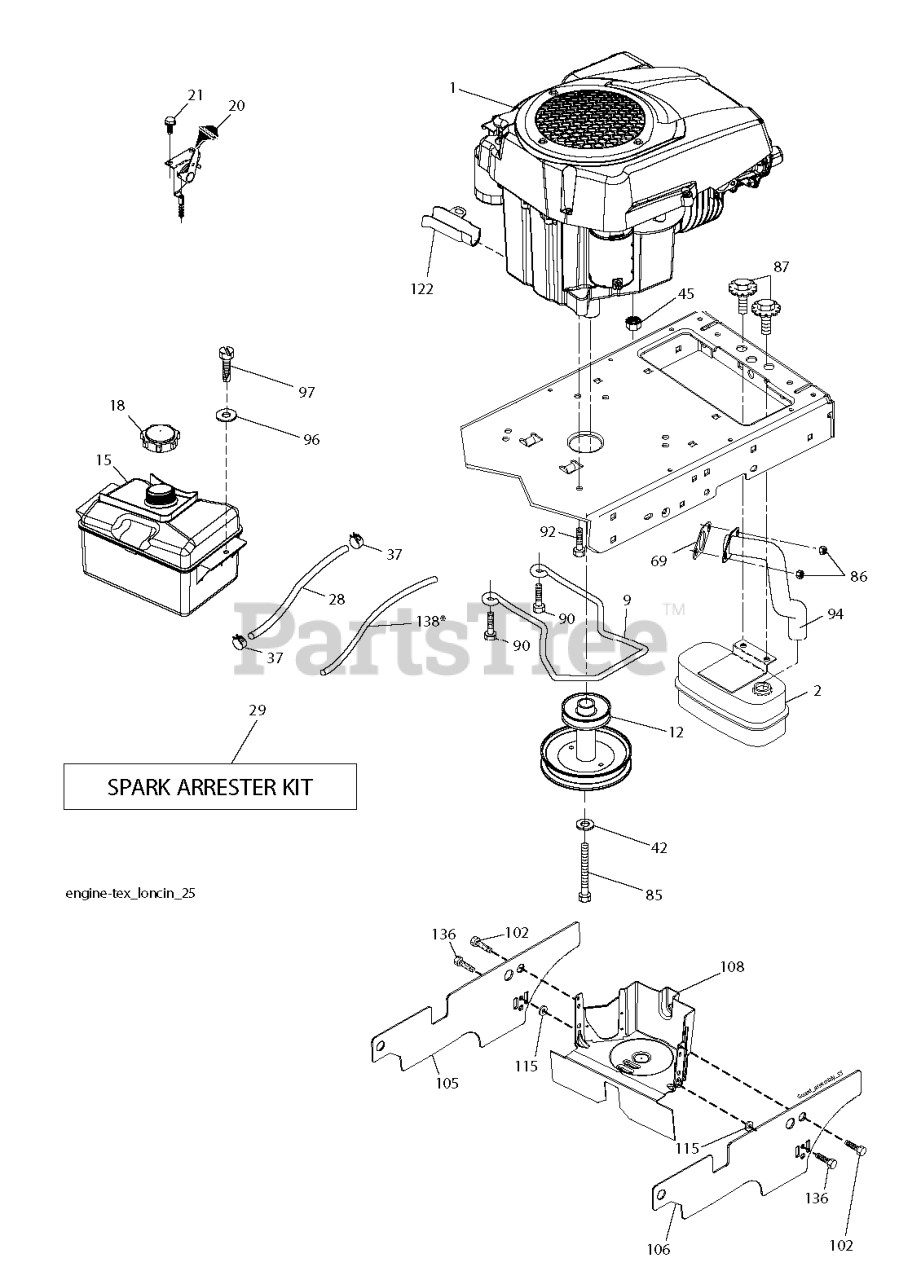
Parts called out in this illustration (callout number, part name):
1	ENGINE.LONCIN.SPARE/452
2	MUFFLER.ASM.SINGLE
12	ENGINE.PULLEY
15	FUEL TANK
15	FUEL.TANK.ASM.NON-EPA
18	CAP.2.25'.VENTED.RATCHET.EPA
20	CONTROL.TH/CK.C.BLACK
28	HOSE 1/4" LOW PERMEATION FUEL
29	KIT.SPARK ARRESTOR 794945 B&S
37	HOSE CLAMP
45	NUT HEXAGON WITH FLANGE, SERRA
69	GASKET GASKET.EXHAUST.LONCIN 3
79	Screws
85	BOLT.HEX.7/16-20X4.GR5.1.5BLUE
86	NUT.HEX.FLANGE.TOPLOCK
87	BOLT.5/16-18UNCX3/4 W/SEMS.BLK
90	SCREW 3/8-16X1
92	SCREW 3/8-16X1
94	TUBE TUBE.EXHAUST.LONCIN 452.T
97	SCREW HEXWSHR 1/4-20X3/4
102	BOLT.HEX.HD.WASHER.5/16-18X.75
105	SHIELD.SIDE.LH.3842"TEX FRN.BK
106	SHIELD.SIDE.LH.3842"TEX FRN.BK
108	COVER ENGINE PULLEY COVER WITH
115	RETAINER
122	EXTENSION DRAIN OIL
136	Screws
